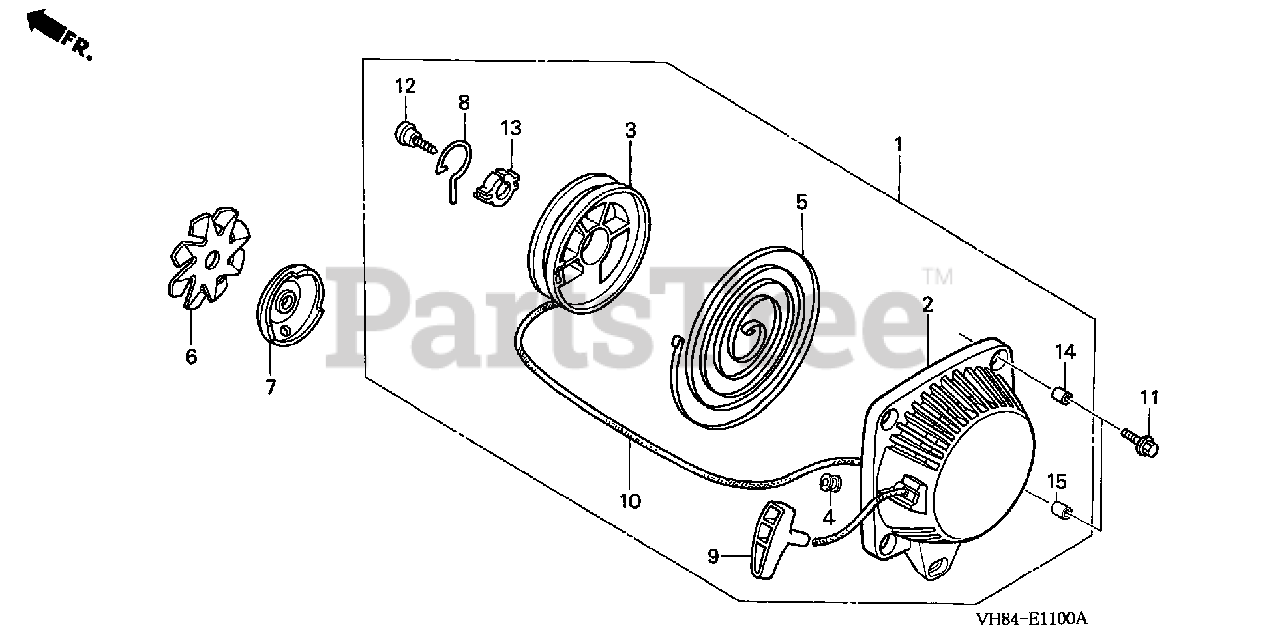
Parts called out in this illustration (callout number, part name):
1	STARTER ASSY., RECOIL *NH1* (BLACK)
2	CASE, RECOIL STARTER *NH1* (BLACK)
3	REEL, RECOIL STARTER
4	GUIDE, ROPE
5	SPRING, RECOIL STARTER
6	FAN, RATCHET
7	PULLEY, RECOIL STARTER
9	KNOB, RECOIL STARTER
10	ROPE, RECOIL STARTER
11	BOLT, FLANGE (5X18)
12	SCREW, SETTING
15	COLLAR A, HEAD COVER
